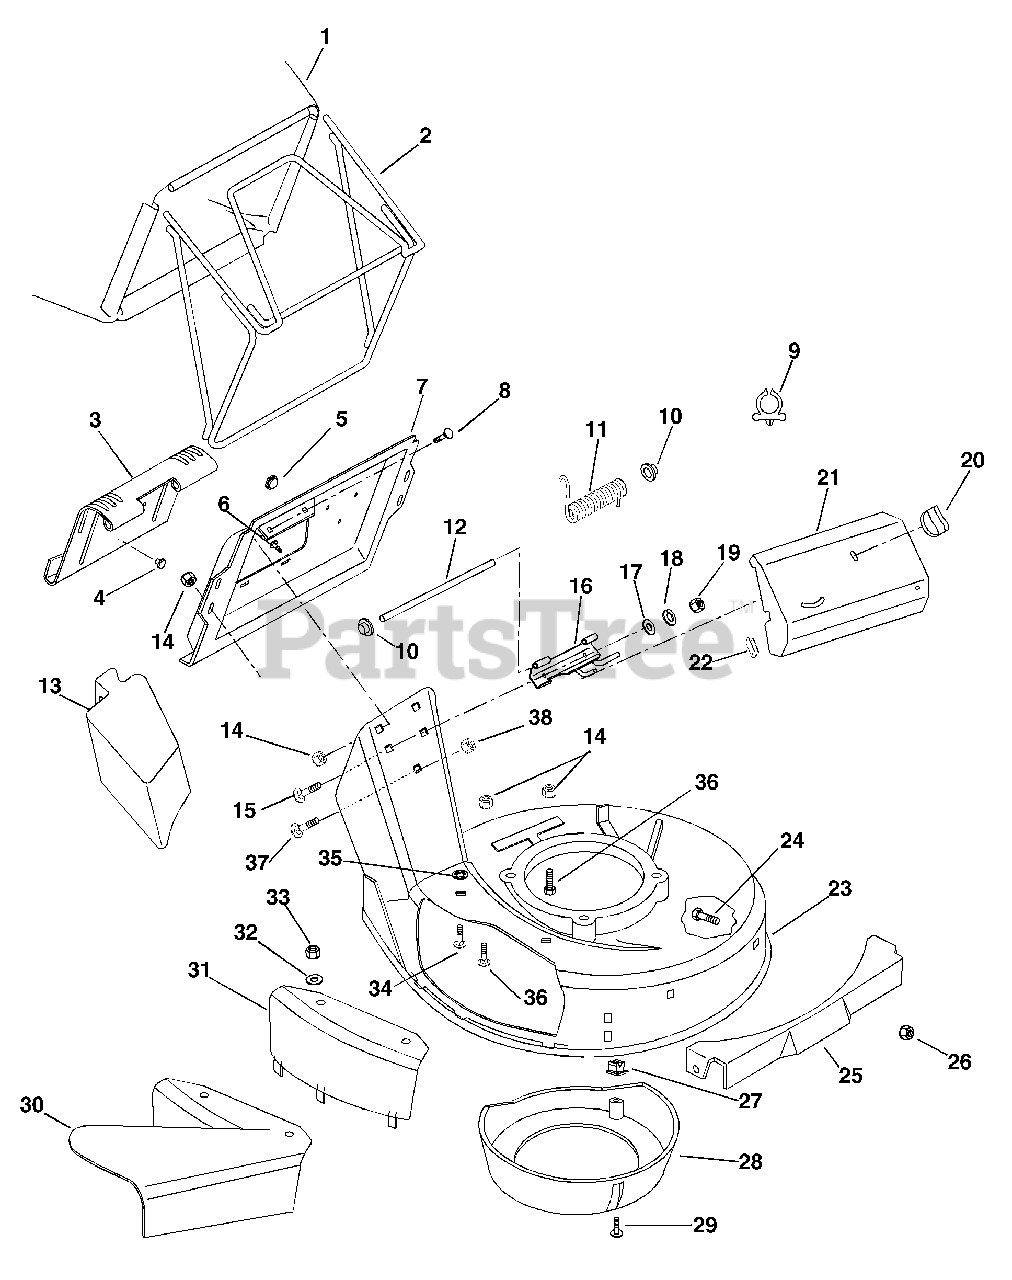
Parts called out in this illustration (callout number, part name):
1	Bag-Consumer Black
2	Bagger Frame
3	Door-Catcher Plate
4	Button Bumper
6	Screw-Tapping 10-24 x .375 Hex Washer Head
7	Plate-Catcher
8	Bolt-Round Head Square Neck .25-20 x .38
9	Snap-in Clip
10	Nut-Push
11	Spring-Torsion .120 x .68 x 3.09
12	Pin-Door
13	Mulch Master Mulcher Accessory
14	Nut-Locking-Flange .25-20
15	Bolt-Round Head Square Neck .25-20 x .75 Grade 5
16	Hinge Base Weldment
17	Washer-Flat-Steel .033 x .087 x .179
18	Washer-Locking .25 x .077
19	Nut-Hex .25-20
20	Nut-Wing
21	Cover-Drive
22	Bumper-Trim
23	Mower Pan Head w/ Decals
24	Bolt-Round Head Square Neck .31-18 x .50
25	Panel-Front
26	Nut-Locking .31-18
27	Grommet-Plastic
28	Baffle-Center
29	Screw-Tapping 10-16 x .62 Hex Washer Head
30	Side Discharge Assembly
31	Side Discharge Cover
32	Washer-Flat-Steel .406 x .812 x .065
33	Nut-Locking-Center .31-18
34	Bolt-Round Head Square Neck .31-18 x .75
35	Nut-Push .312
36	Bolt-Hex .25-20 x .50 Grade 5
37	Bolt-Round Shank Square Neck .38-16 x .75 Grade 5
38	Nut-Locking-Center .38-16
